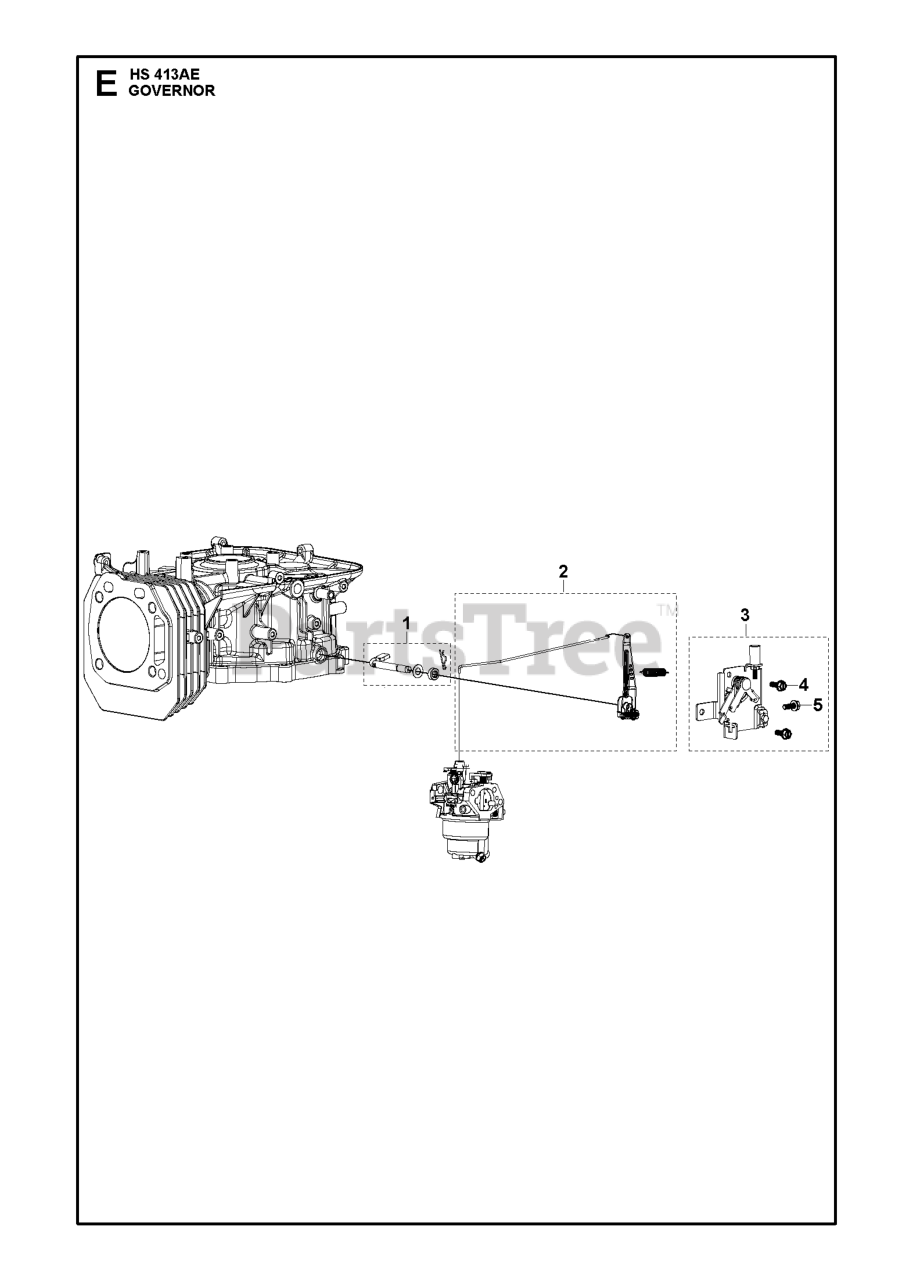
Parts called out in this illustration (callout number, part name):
1	SERVICE KIT KIT.SPEED REGULATI
3	THROTTLE HANDLE THROTTLE HANDL
4	Husqvarna TBD
